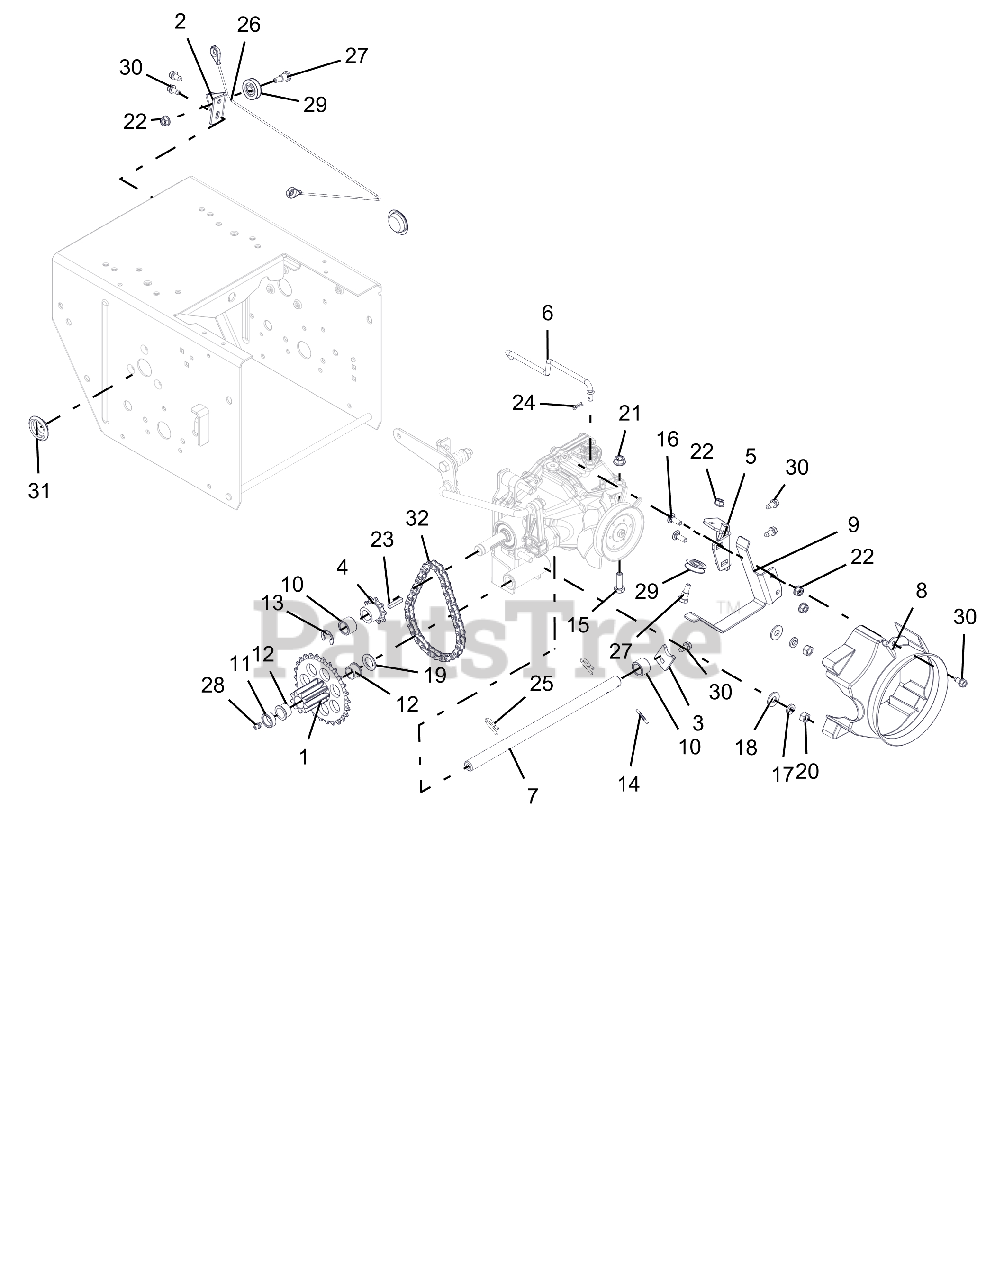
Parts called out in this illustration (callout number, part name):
1	PINION & SPROCKET
2	BRACKET, CABLE PULLEY
3	TAB, ANTI ROTATION
4	SPROCKET, PINION 9T W/KEY
5	BRACKET, CLUTCH CABLE
6	ROD, HYDRO BYPASS
7	SHAFT, PINION - HARDENED
8	SHROUD, HYDROGEAR RT-310
9	FINGER, BELT - FLAT
10	SPACER, .635X.880X.611
11	BSHG-SLV, .635X.880X.305
12	BSHG-FLG .625X.750X.500X.875
13	RG-RTNG-EXT .625X.042
14	@PIN-GRV .125X1.00 TP E ALLOY
15	@BLT-HEX .31-18X1.00 GR5 YWZC
16	@BLT-RDHDSQNK .25-20X.75 G5YZ
17	WSHR-LK .312X.097 HVY YWZC
18	@WSHR-FL-STL.38X.875X.083 YWZC
19	WSHR-FL-STL .630X1.005X.062 YZ
20	@NUT-HEX .31-18 YWZC
21	@NUT-LK-TOP-FLG .31-18 YWZC
22	@NUT-LK-TOP-FLG .25-20 YWZC
23	KEY-SQ .188X1.0X.188 SAE 8630
24	PIN-HAIR INT .06X.18X.77
25	PIN, SPRING CLIP
26	CABLE, TRACTION, HYDRO PRO
27	BOLT, SHLDR-.375X.375X.25-20
28	ZERK,FITTING .25X.125 DRIVE IN
29	PULLEY, CABLE
30	SCR-TAP .25-20X.50 HWH TR YWZ
31	PLUG, HOLE - 1.125"
32	CHAIN - #41, 32 PITCHES
